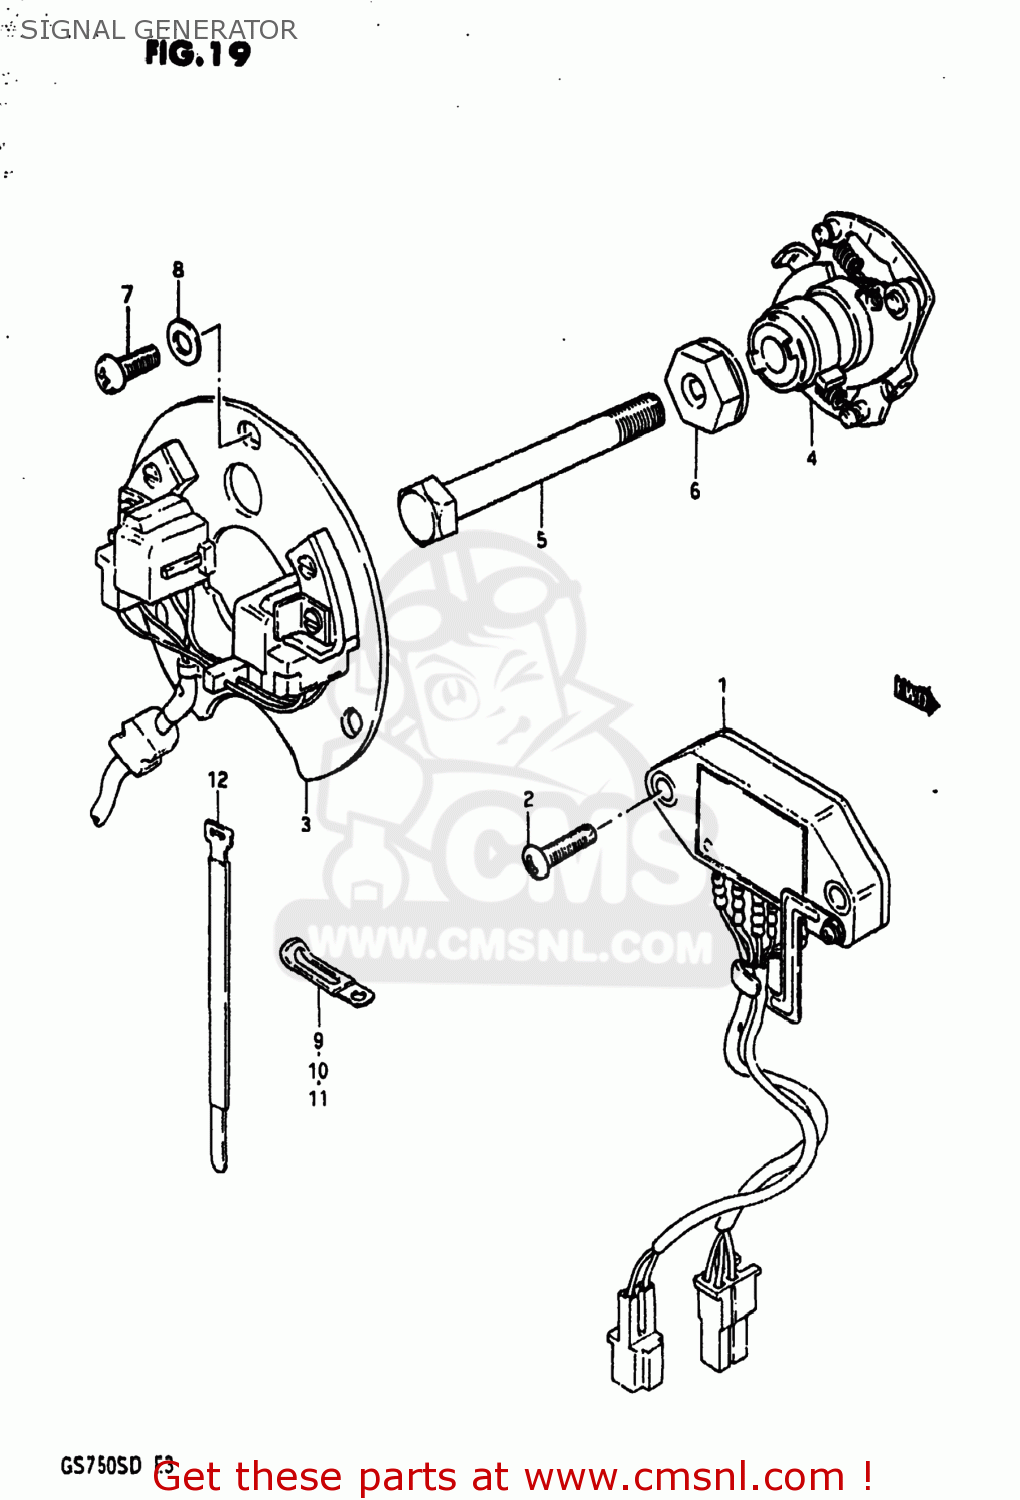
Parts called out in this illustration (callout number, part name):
1	IGNITER UNIT
2	SCREW
3	SIGNAL GENERATOR ASSEMBLY
4	GOVERNOR ASSEMBLY
5	BOLT
6	WASHER
7	SCREW(5X12)
8	WASHER
9	CLAMP L:35
10	CLAMP
11	CLAMP
12	CLAMP
